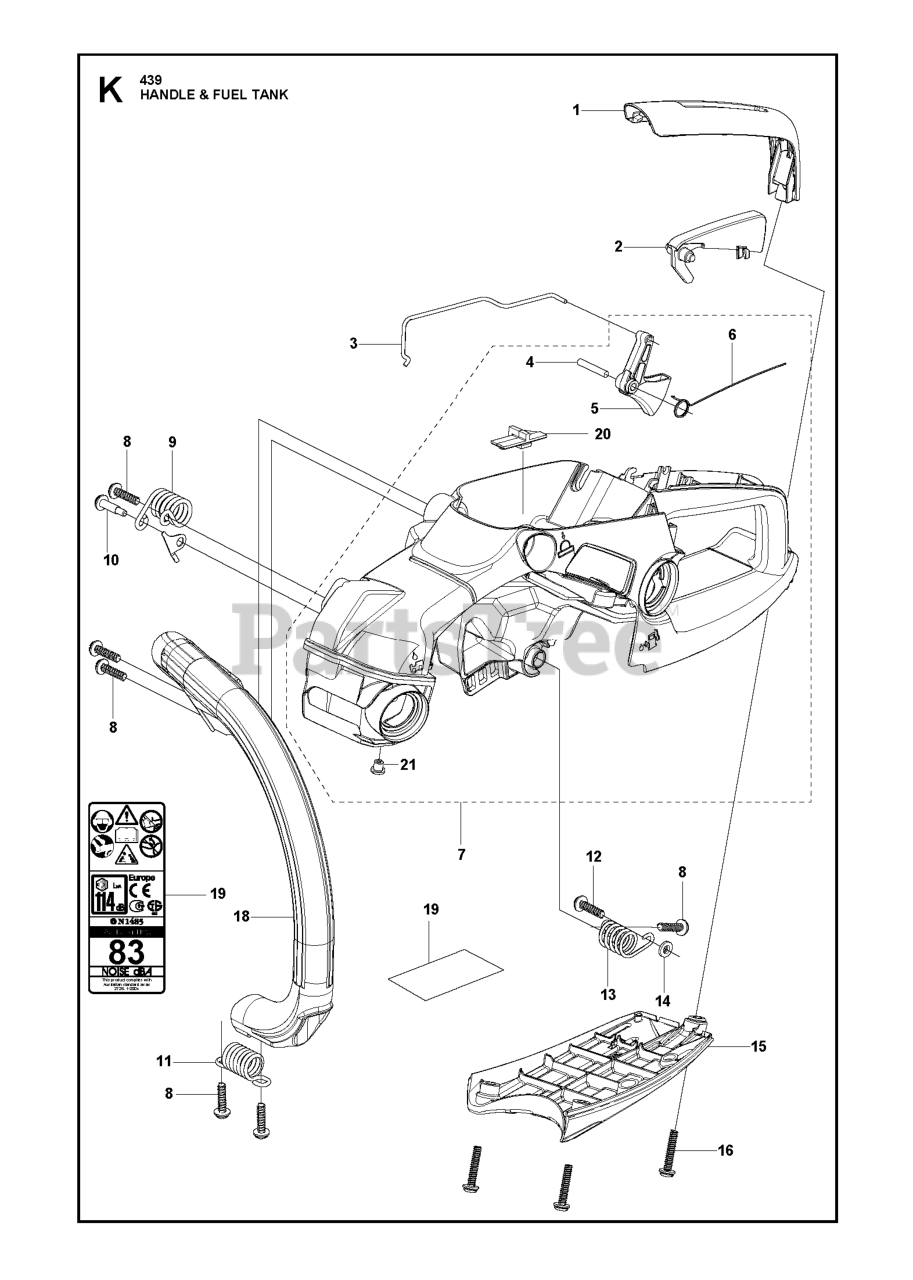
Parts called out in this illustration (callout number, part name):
1	COVER GRIP 439
3	THROTTLE ROD 436/GZ3500L
4	PIN 8488B42400
5	THROTTLE LEVER
6	SPRING
7	HANDLE ASSY 439
9	SPRING FRONT 439
11	SPRING FLYWHEEL SIDE
12	SCREW (RPLS 267132210)
13	SPRING, PTO
14	SPACER Z114283110
15	COVER HANDLE 439
18	FRONT HANDLE 439
19	DECAL WARNING 439
20	GROMMET R HANDLE
